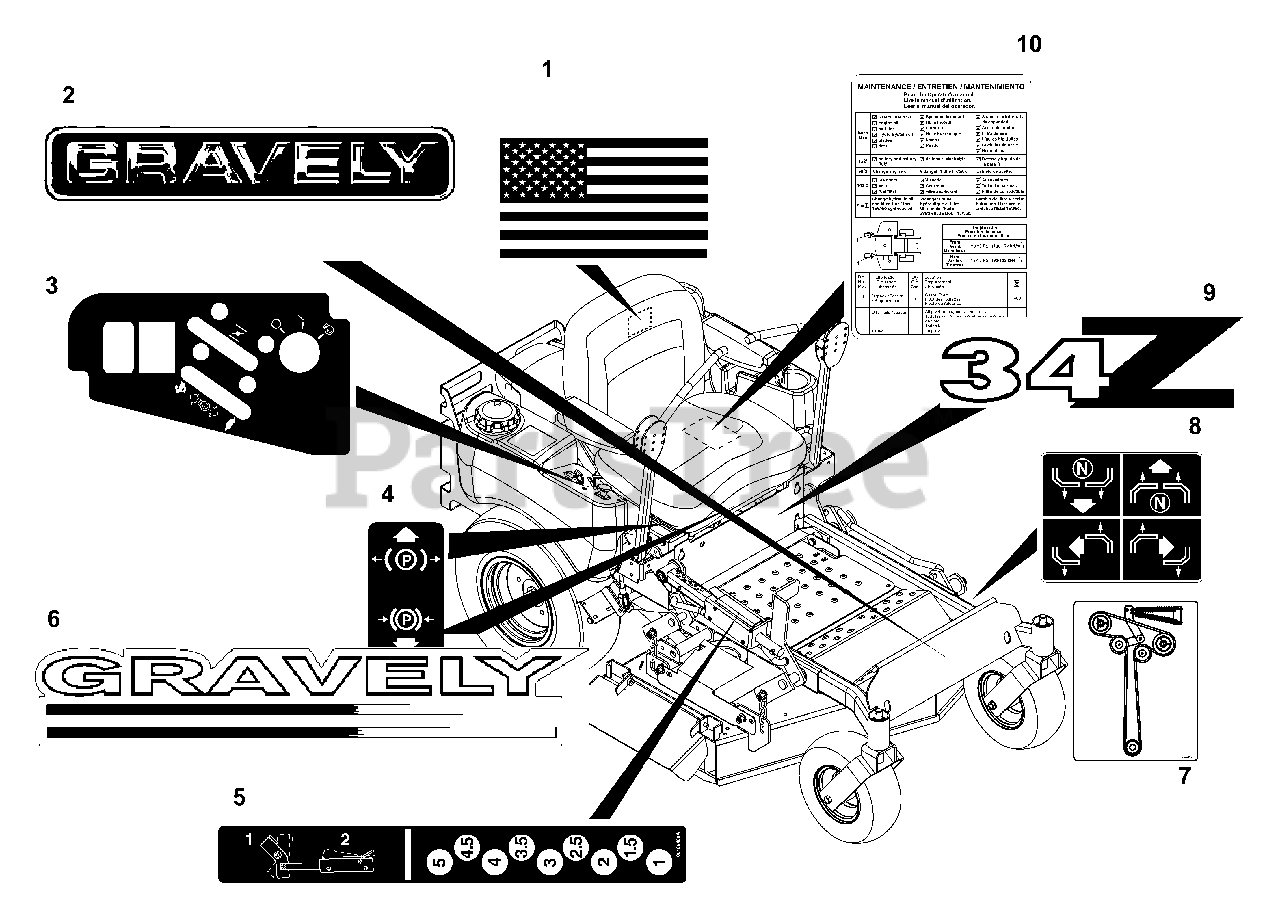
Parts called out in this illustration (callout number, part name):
1	Decal, American Flag
2	Decal, 15" Gravely Logo
3	Decal, Control Panel
4	Decal, Parking Brake Lever
5	Decal, Height of Cut
6	Decal, ZT Hood
7	Decal, Belt Diagram
8	Decal, Instructional Steering
9	Decal, PM 34Z
9	Decal, PM 44Z
10	Decal, Service Instructions
